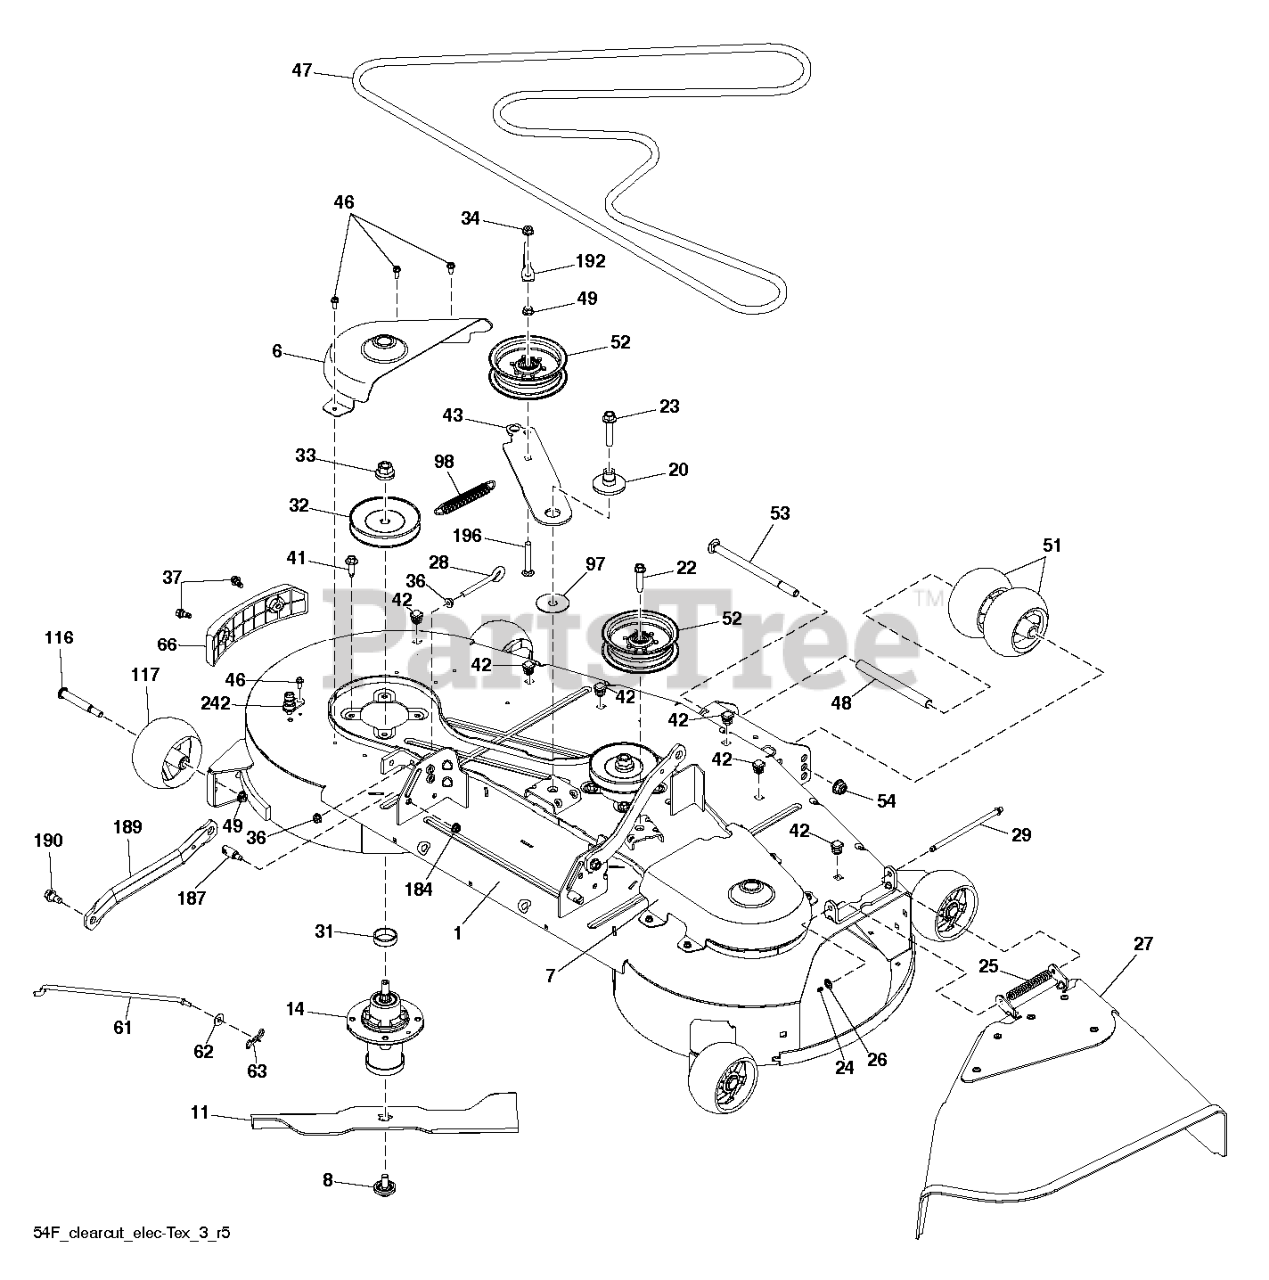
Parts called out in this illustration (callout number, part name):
1	SERVICE KIT KIT.SVC.WELDMENT.5
6	COVER 54 CLEARCUT, LH MANDREL,
7	COVER 54 CLEARCUT RH MANDREL G
8	BOLT.WASHER.ASM.7/16-2
11	BLADE CC54 PZ STYLE HI LIFT BL
11	BLADE.54CC.HI-LIFT.PZ.165".668
14	MANDREL ASM, CAST IRON
20	SPACER.IDLER.PULLY.HUB
23	SCREW.7/16-14 X 2.125.WASHER
24	CAP-SLEEVE LT
25	SPRING.42.FCS.DEFLECTOR
26	NUT PUSH M
27	DEFLECTOR ASSY 54 CLEARCUT RES
28	GSPW Bolts
31	WASHER.SPACER.MANDREL
32	MANDREL.PULLEY.38.BRIGHT.ZINC
32	PULLEY MANDREL
36	GSPW Hardware
37	SHOULDER BOLT 5/16-18TT
41	BOLT.HEX.WASHR.HED.313-18X1.19
42	Plugs
43	ARM IDLER ARM, CLEARCUT 54 BLA
46	SCREW.1/4-20X5/8
47	BELT CLEARCUT 54, TRACTOR DECK
49	NUT.HEX.FLANGE.3/8-16.LOCKNUT
51	ROLLER, GAUGE .635 BORN
52	PULLEY.IDLER.2006
54	NUT 1/2-13 HEX FLANGE NYLOK CL
62	Washers
62	GSPH
63	PIN.COTTER.5/16.BOW TI
66	BUMPER ASSY 54 CLEARCUT TRIM S
98	SPRING.EXTN.42.FCS.TR.DECK.DRV
117	WHEEL.GAUGE.RALLY
187	STUD.W/"D"ANTI-ROTATION
189	ARM.RFIXED.MOWER.SUSPNSIONX431
189	SERVICE KIT ARM ARM.SUSPENSION
190	BOLT.SHOULDER
192	KEEPER.BELT.IDLER.54"T
196	CARRIAGE BOLT 3/8-16 X
242	PORT.WASHOUT
